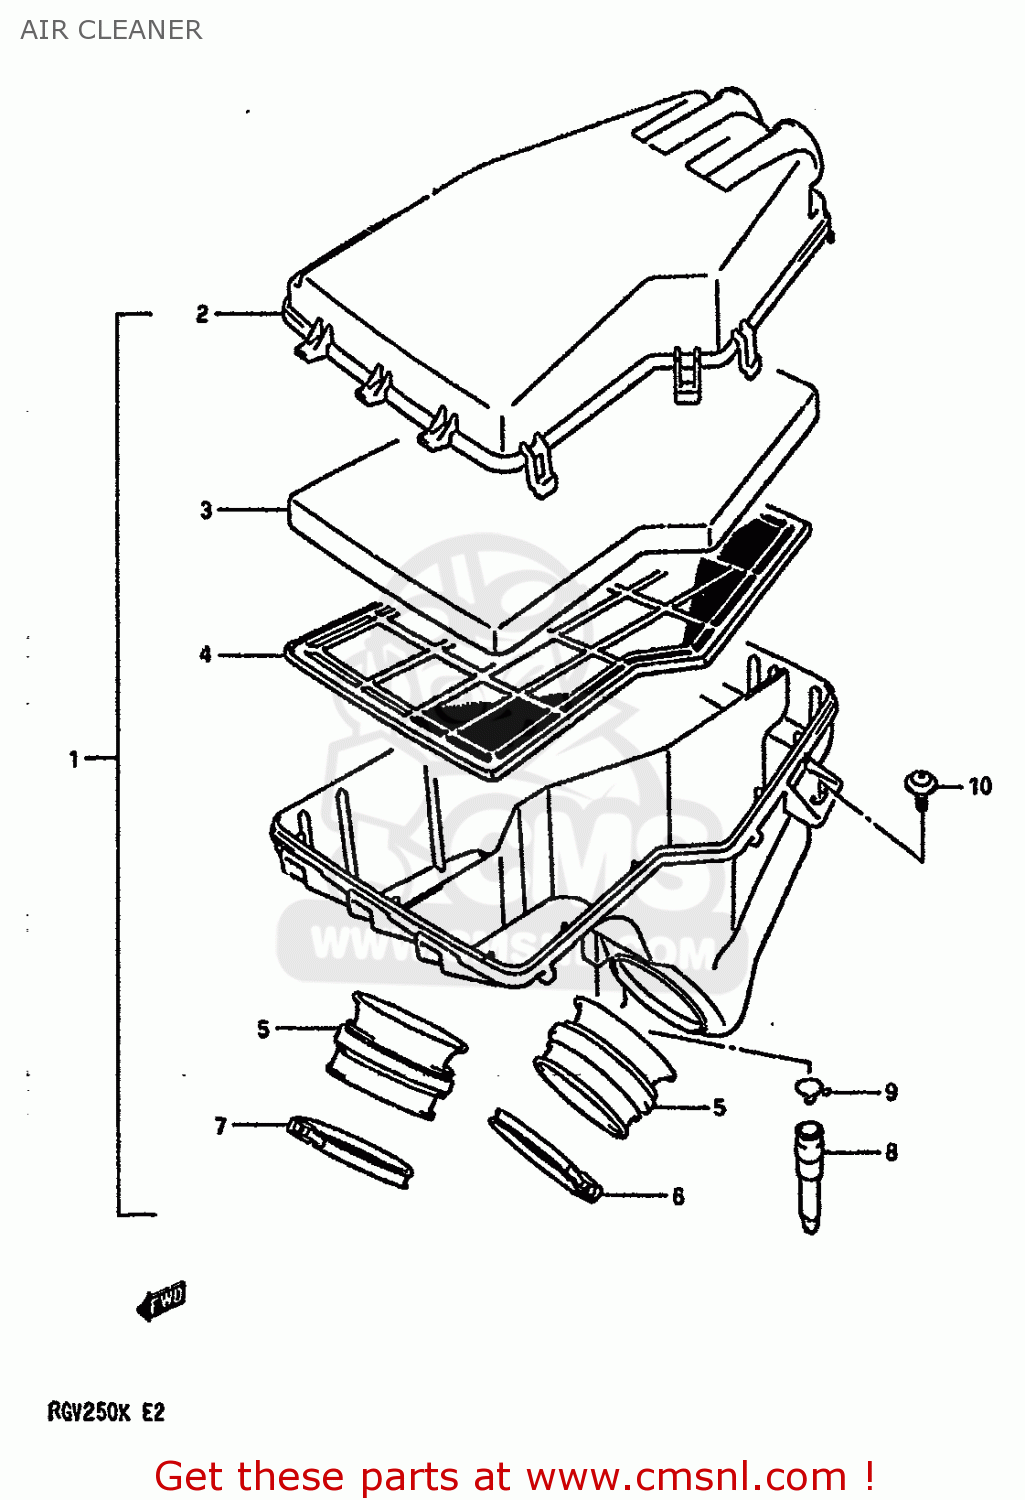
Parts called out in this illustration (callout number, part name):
1	CLEANER ASSY,AIR
2	CAP,AIR CLEANER
3	FILTER
4	TRAP
5	TUBE,OUTLET
6	CLAMP
7	CLAMP
8	CAP,DRAIN
9	CLIP
10	SCREW(6X16)
